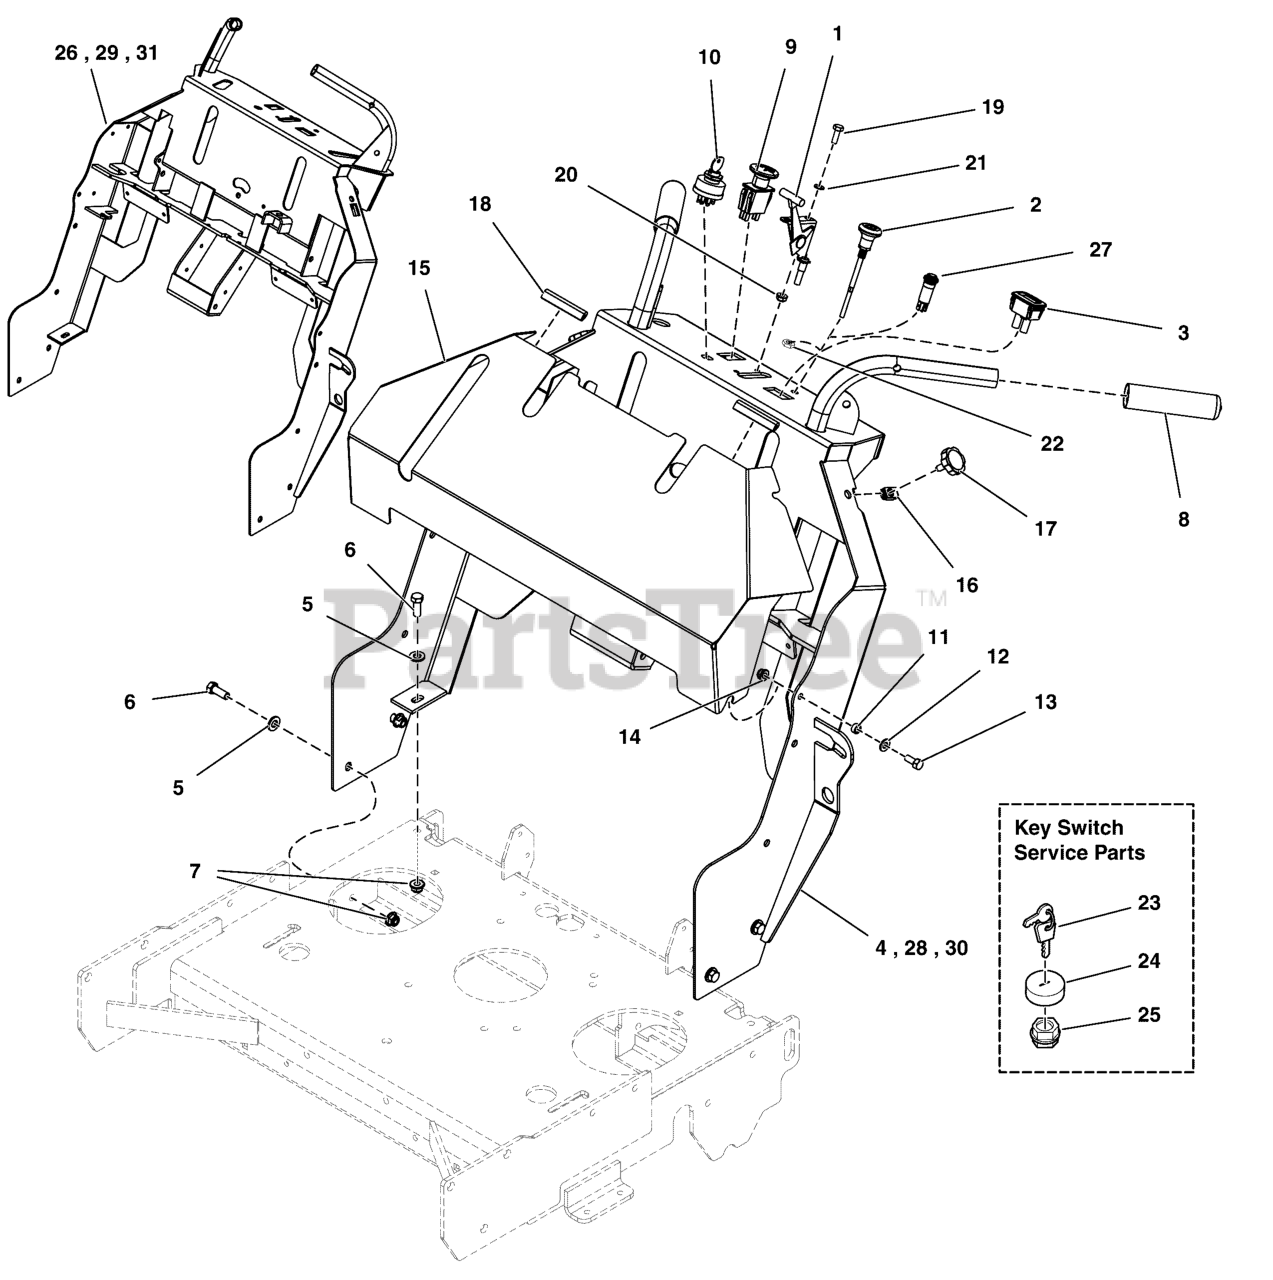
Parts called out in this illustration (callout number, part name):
1	CABLE, THROTTLE, 43" DETENTED
2	CABLE, CHOKE CONTROL, 43.5"
2	CABLE, CHOKE CONTROL, 43.5", DETENTED
2	CABLE, CHOKE CONTROL, 51" (Z)
3	HOUR METER
4	** WELD, HANDLE BARS, WALK - RED
4	** WELD, HANDLE BARS, F/SW35 - RED
5	WASHER, 3/8" GR. 9 FLAT
6	BOLT, 3/8-16 X 1" GD5 CZ
7	NUT, 3/8 - 16 HEX NYLOCK FLANGE
8	GRIP, FOAM, .940" X 4.62" X .187"
9	PTO SWITCH, MOMENTARY, SMALL KNOB
10	SWITCH, Ignition, Complete
10	SWITCH, IGNITION, 6 POST
11	SPACER, .33 X .50 X .25, PM, CZ
12	WASHER, 5/16" SAE
13	BOLT, 5/16-18 X 1" GRD5 YZ
14	NUT, 5/16-18 HEX NYLOCK FLANGE NUT
15	ASSM, HB GUARD W/DECALS, SW35 - DOM (5412377B)
16	BODY CLIP, 5/16-18-7GA MATERIAL
17	KNOB, 5/16-18 X 1.00, ROSETTE, BLK
18	BLACK BODY MOLDING, 3" LONG
19	BOLT, 1/4"-20 X 3/4" GD5 YZ
20	NUT, 1/4-20 Hex Nylock Flange
21	WASHER, 1/4 SAE
22	NUT, 3/8-24 Hex Jam
23	KEY, IGNITION MOLDED SET
24	COVER, PLASTIC, SNAP ON
25	PLASTIC NUT
26	** WELD, HANDLE BAR, SW35/FW35, CC - RED
27	LIGHT, INDICATOR, PANEL, LED, RED
28	** WELD, HANDLE BARS, F/SW35 - RED
29	** WELD, HANDLE BAR, SW35/FW35, CC - RED
30	WELD HANDLE BARS W35 - RED
31	**WELD, HANDLE BARS, W35, CC - RED
